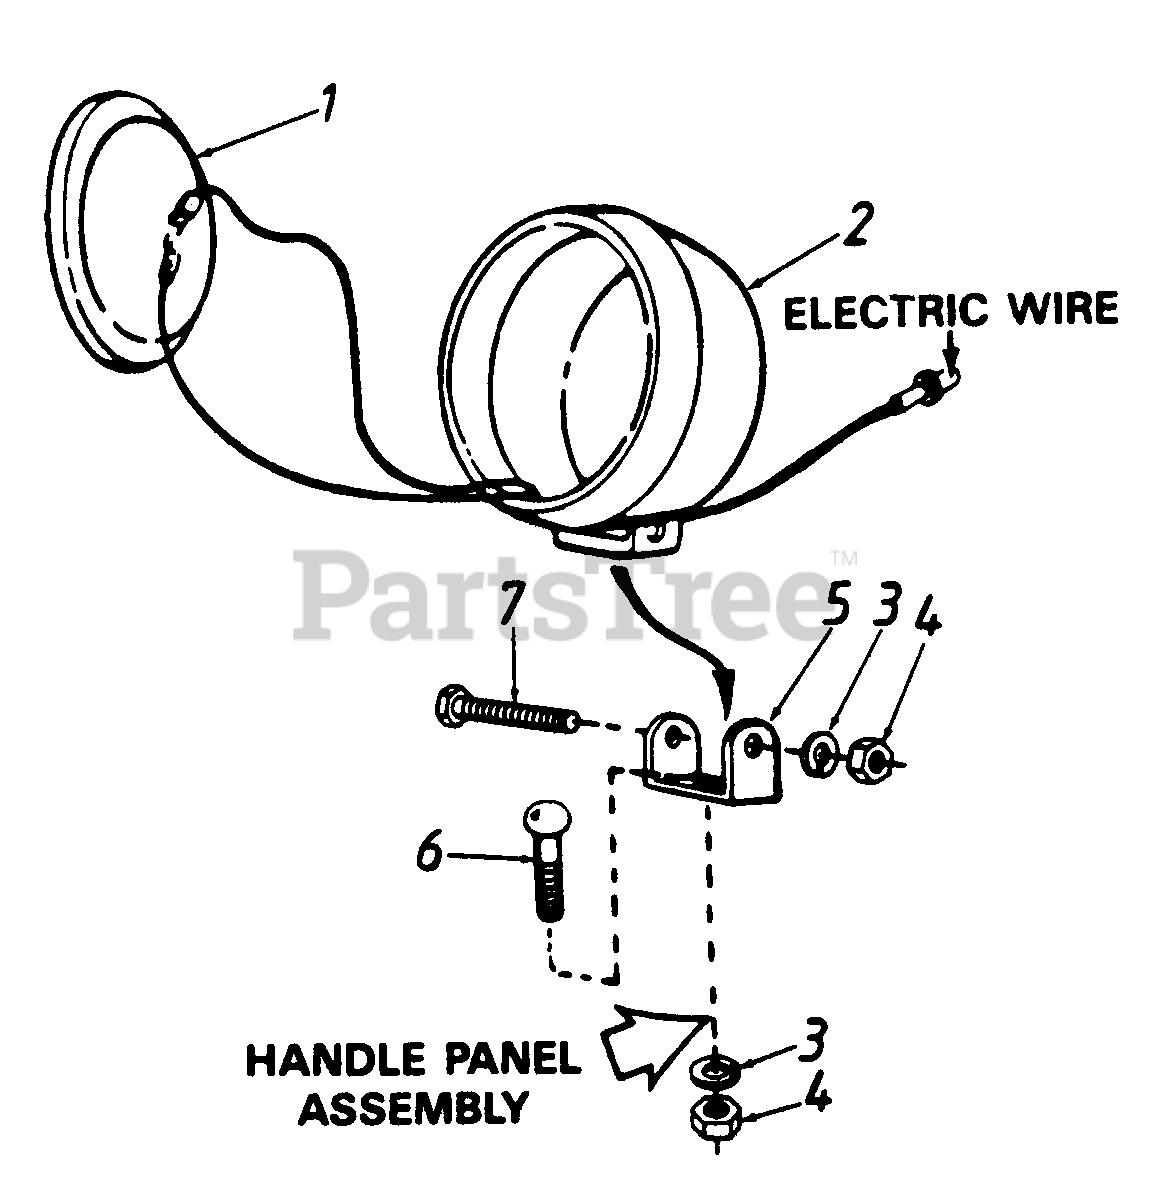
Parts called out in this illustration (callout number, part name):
1	Sealed Beam Headlight
2	Lamp Assembly
3	L.-Wash. 5/16" I.D.*
4	Hex Nut 5/16-18 Thd.*
5	Lamp Mounting Bracket
6	Carriage Bolt 5/16-18 x 1"
7	Hex Bolt 5/16-18 x 2"*
